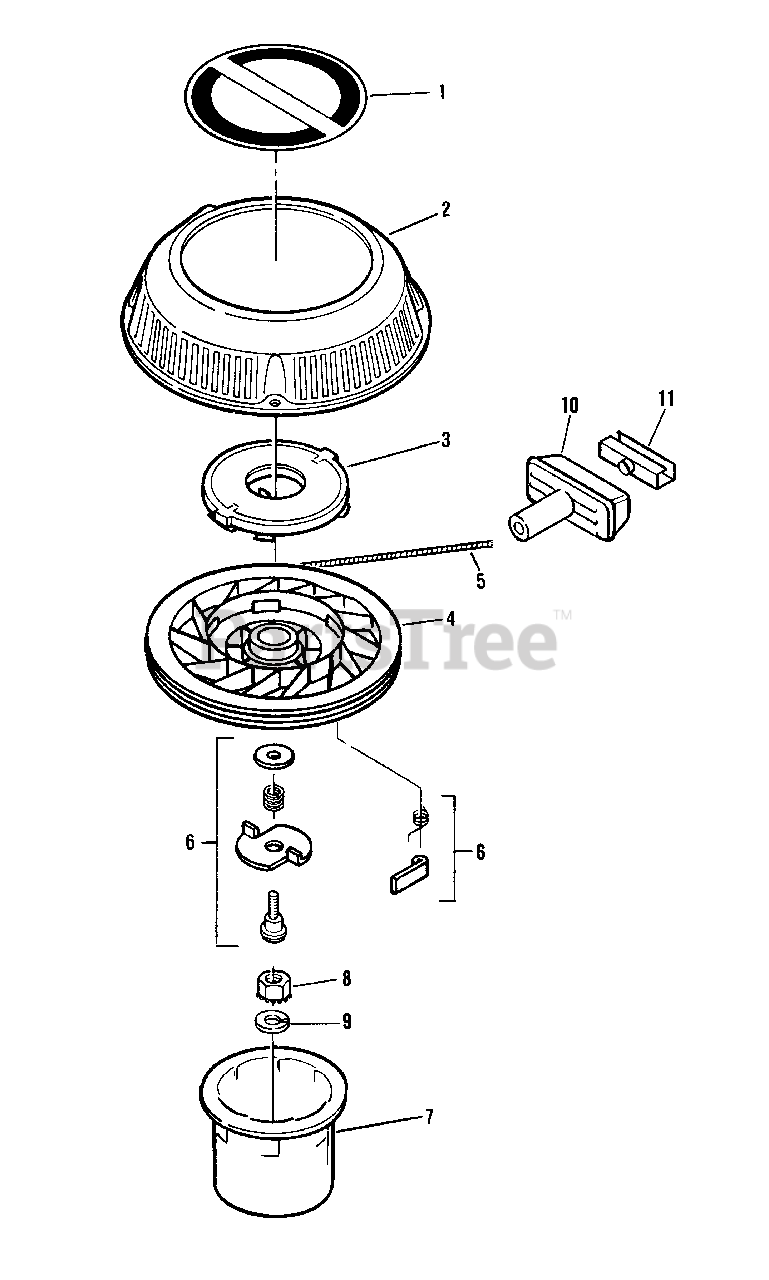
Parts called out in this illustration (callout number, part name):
1	Decal
2	Starter Housing and Shaft
3	Recoil Spring and Keeper
4	Pulley
5	Rope
6	Dog Kit Assembly
7	Starter Hub
8	Nut-Flywheel
9	Lockwasher-Flywheel
10	Handle-Starter
11	Clip-Rope Insert
